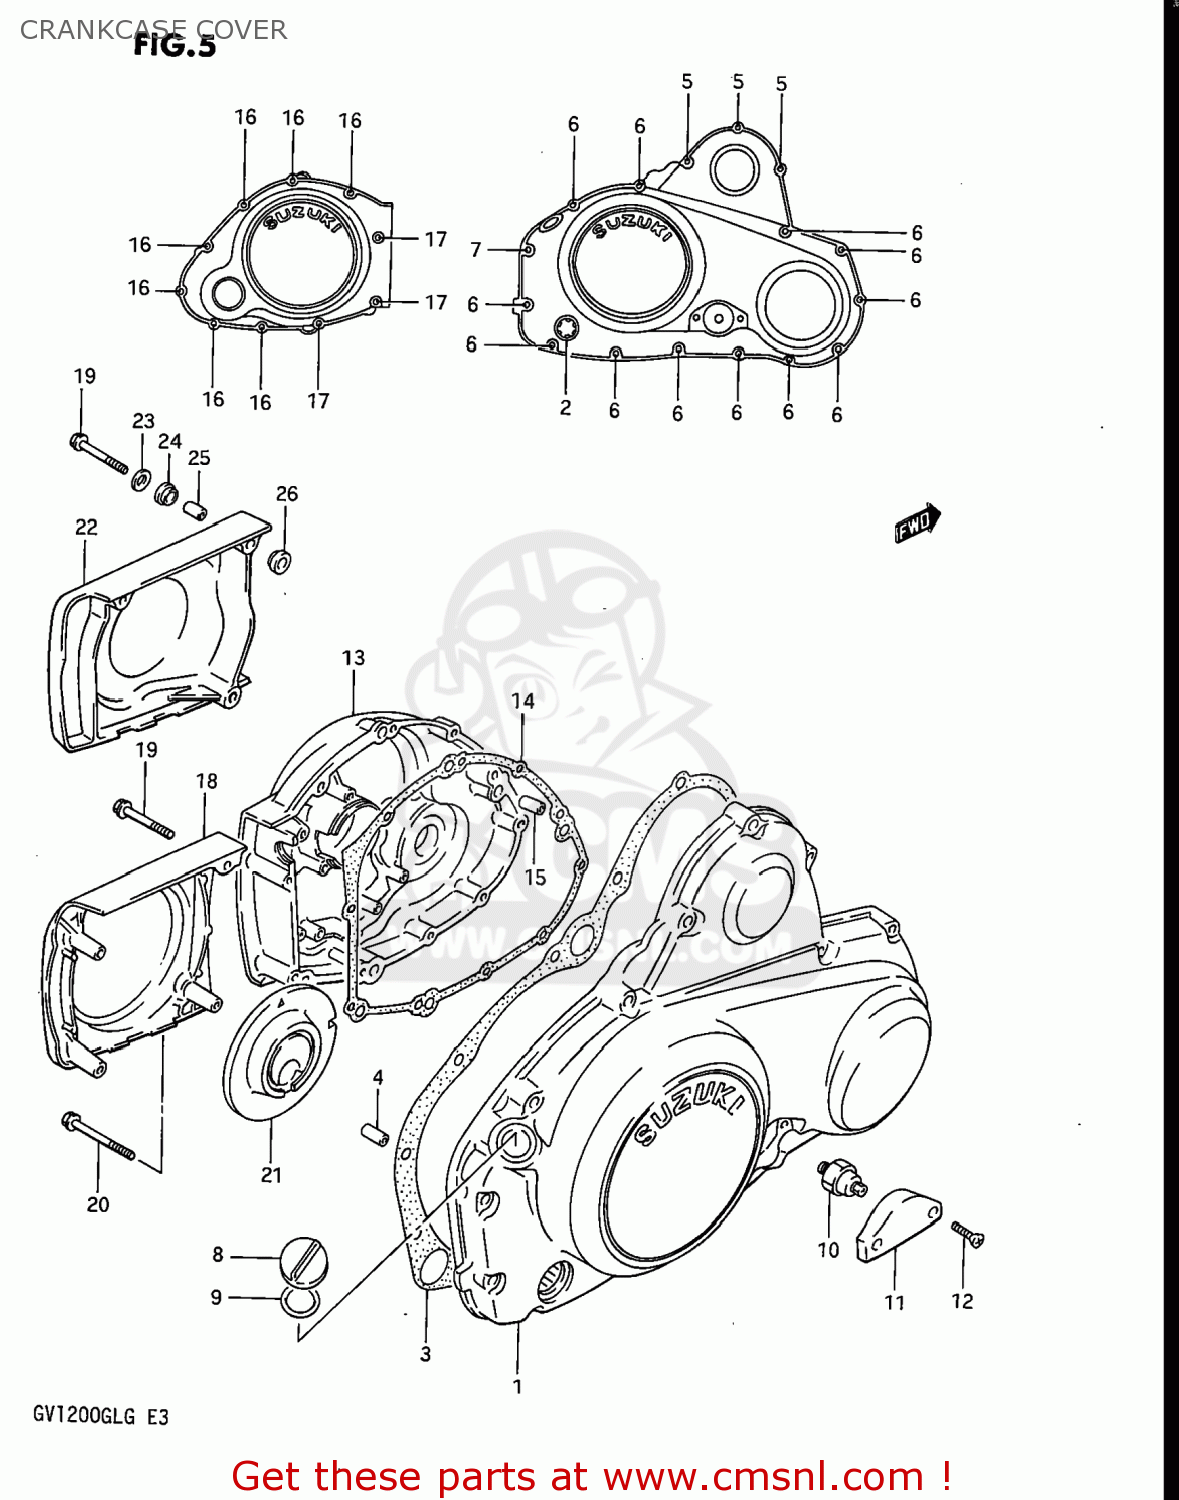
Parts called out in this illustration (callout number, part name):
1	COVER,CLUTCH
2	LENS,OIL LEVEL CHECK
3	GASKET,CLUTCH COVER (MCA)
4	PIN
5	BOLT 6X30
6	BOLT
7	BOLT
8	PLUG(20X10)
9	O RING(D:3.1,ID:16.8)
10	SWITCH ASSEMBLY
11	CAP,OIL PRESSURE SWITCH
12	SCREW (L:20)(SUS)
13	COVER,GENERATOR
14	GASKET,MAGNETO COVER (MCA)
15	PIN (11X20)(SUS)
16	BOLT
17	BOLT
18	COVER,SECONDARY DRIVE
19	BOLT
20	BOLT
21	DAMPER
22	COVER,SPROCKET
23	WASHER
24	WASHER(8.7X15X2.1)
25	SPACER (6.1X9X26.3)
26	WASHER(8.7X16X5)
